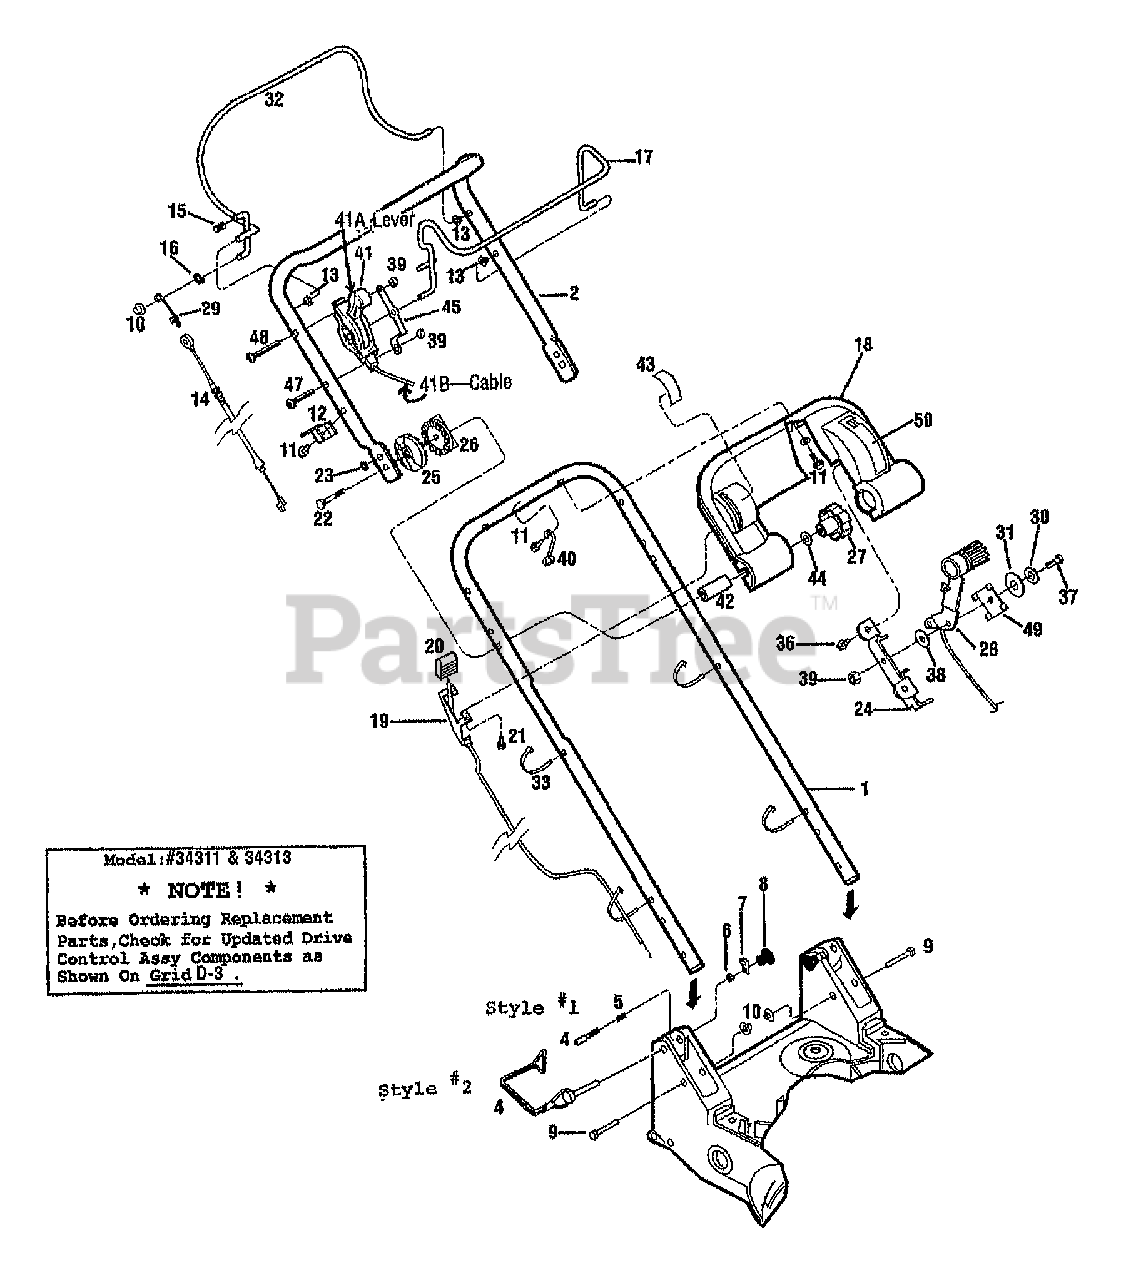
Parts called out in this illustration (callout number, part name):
1	HANDLEBAR-LOWER PNT
2	HANDLEBAR-UPPER PNT
4	PIN-STOP
4	PIN-LK SQ. #W51620LP
5	SPRING-COMPRESSION
6	NUT-HEX 1/4-20 ZP
7	ARM-STOP ZP BLACK CHRMATE
8	KNOB
9	PIN-CLEVIS ( @DEPL)
10	CAP-PUSH .312
11	SCR-FLANGE 1/4-20X3/4 GR5
13	BUSHING-PLASTIC (BAIL)
14	CABLE-CONTROL DR BBC MM
15	HANDLE GRIP
16	GRIP-RING EXT .312 ID
17	BAIL-CONTROL PNT
18	CONSOLE-HANDLEBAR
19	CABLE-THROTTLE
20	KNOB-WHEEL DRIVE CABLE
21	SCR-M10-16X.88 SPECIAL
22	SCR-CARR 5/16-18X4.56
23	RETAINER .25
24	SUPPORT-CONTROL
25	QUADRANT-OUTER (WAS 1767425)
26	KIT-QUADRANT INNER (WAS 1767375)
27	KNOB-HANDLE ADJUST
28	KIT-DRIVE CABLE MULCHER
29	SPRING-EXTENSION
30	WASHER-BELLEVILLE
31	WASHER-1.0X.25X.06 ZP
32	BAIL-CONTROL VINYL COATED
33	TIE-CABLE
36	SCR 1/4-15X.88 SPECIAL
37	SCR-RH 1/4-20X.75
38	BUSHING-NYLON
39	NUT-HT LK 1/4-20
40	GUIDE-ROPE
41	KIT-BLADE CONTROL LEVER
41A	CONTROL-BLADE LEVER
41B	CABLE-CONTROL BBC MM
43	DECAL-THROTTLE W/STOP
44	WASHER-#.75X.32X.09 ZP
45	BRKT-MOUNTING
47	SCR-HH 1/4-20X1.25
48	SCR-HH 1/4-20X2.25
49	CLAMP-BRKT PNT
50	DECAL-CONSOLE BBC MM
